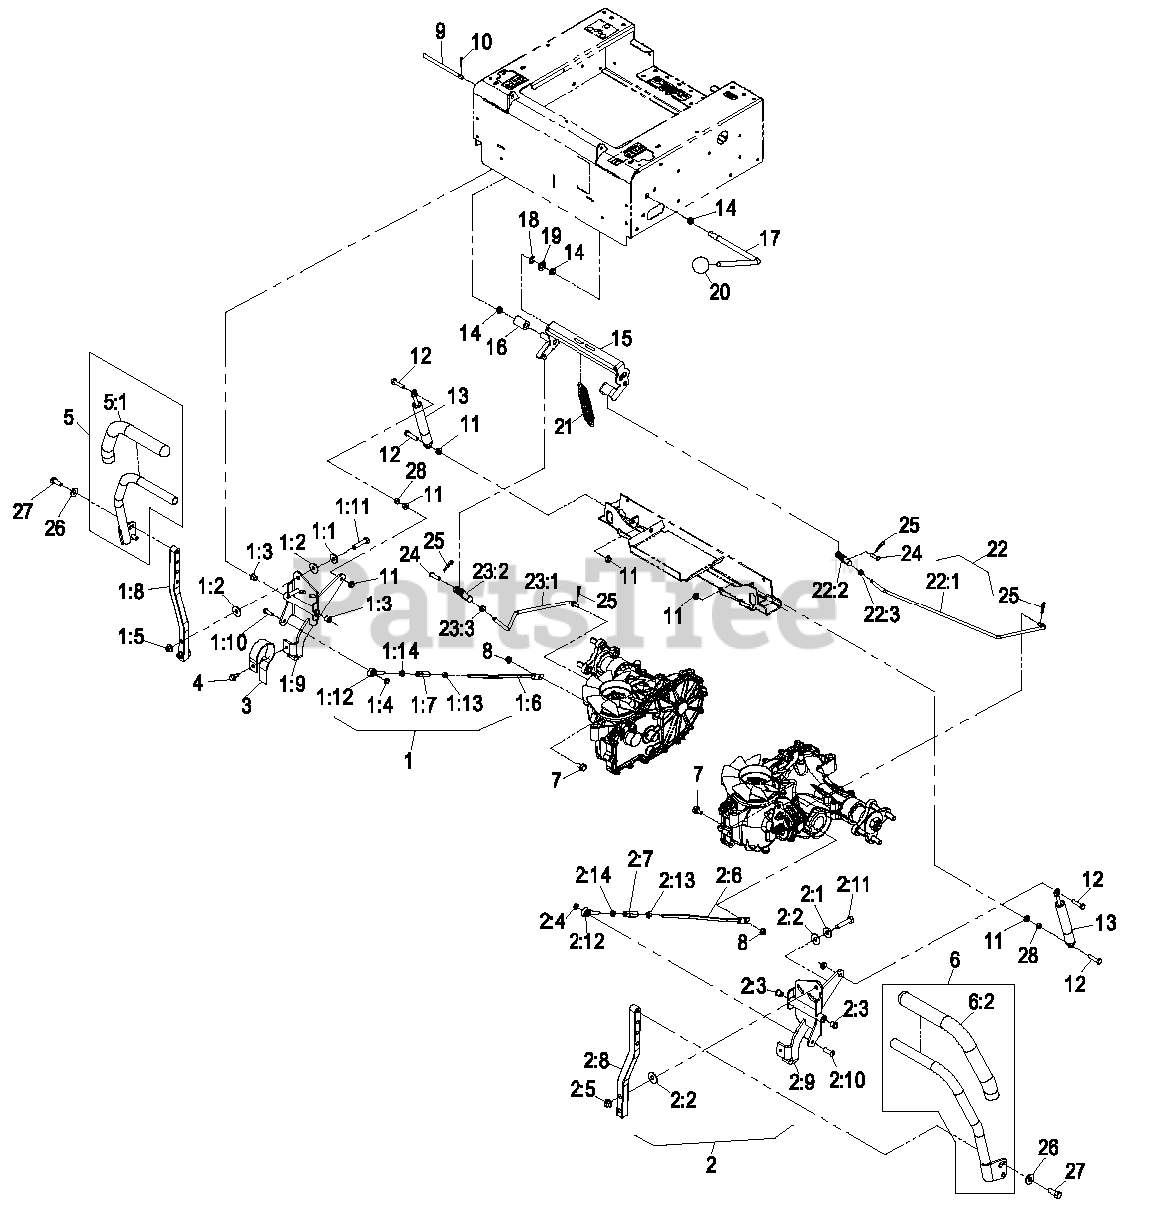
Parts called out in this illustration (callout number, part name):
1	Asm, Motion Control Rh
1:1	WASHER
1:2	WASHER-PLASTIC
1:3	BEARING
1:4	NUT-LOCK, NI
1:5	NUT-HF, NI
1:6	LINK,MOTION CONTROL
1:7	NUT-ROD ADJUSTMENT
1:8	ARM-MOTION CONTROL
1:9	RH CONTROL PIVOT ASM
1:10	SCREW-HSBH
1:11	SCREW-HH
1:12	BEARING-ROD END, LH
1:13	NUT-JAM
1:14	NUT-JAM
2	Asm, Motion Control Lh
2:1	WASHER
2:2	WASHER-PLASTIC
2:3	BEARING
2:4	NUT-LOCK, NI
2:5	NUT-HF, NI
2:6	LINK,MOTION CONTROL
2:7	NUT-ROD ADJUSTMENT
2:8	ARM-MOTION CONTROL
2:9	LH CONTROL PIVOT ASM
2:10	SCREW-HSBH
2:11	SCREW-HH
2:12	BEARING-ROD END, LH
2:13	NUT-JAM
2:14	NUT-JAM
3	SPRING-LEAF
4	Screw-HWH 5/16-18 X 3/4 Tf
5	RH CONTROL HANDLE ASM
6	LH CONTROL HANDLE ASM
7	RH CONTROL HANDLE ASM
8	NUT-HF, NI
9	PIN-CONTROL PIVOT
10	PIN-COTTER
12	SCREW-HH
13	DAMPER-MOTION CONTROL
14	BUSHING,SNAP
17	HANDLE,BRAKE
18	RING-RETAINING, EXTERNAL
19	WASHER-FLAT
21	SPRING-DECK, ENGAGEMENT
22	BRAKE LINKAGE ASM-LH
23	BRAKE LINKAGE ASM-RH
24	PIN-CLEVIS
25	PIN-COTTER
26	WASHER-BELLEVILLE
27	SCREW-HH
28	NUT-HEX
